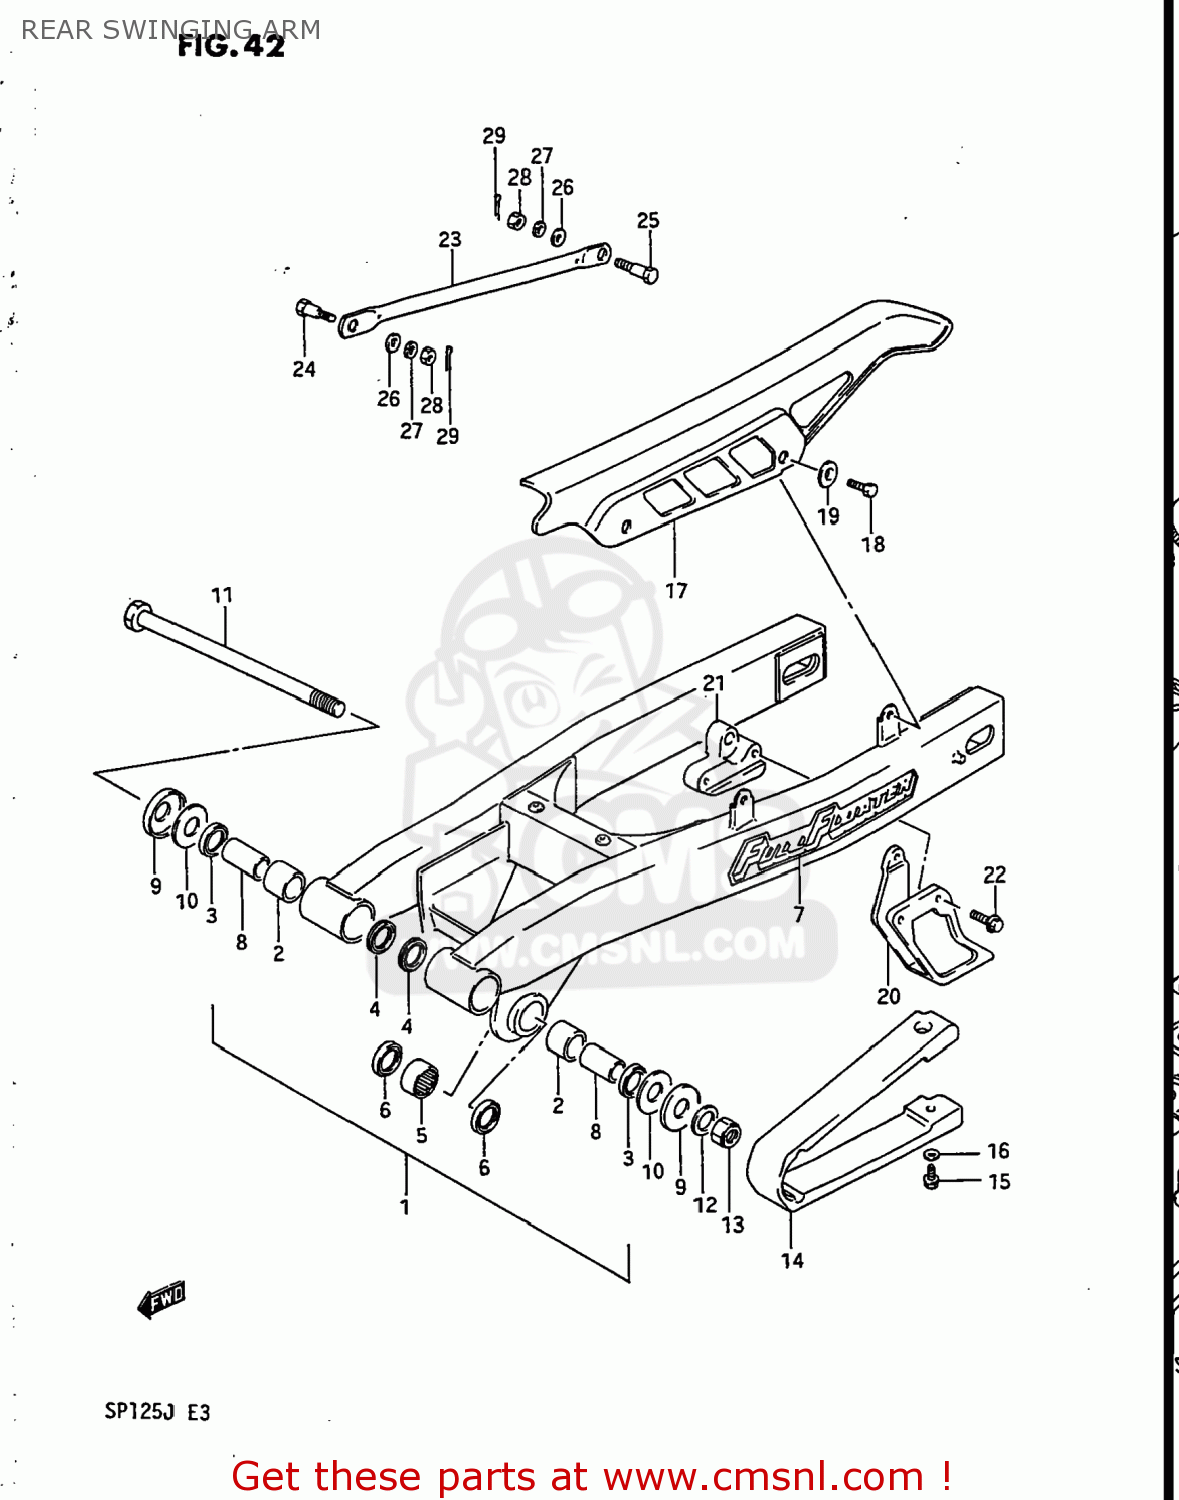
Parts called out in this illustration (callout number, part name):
1	SWING ARM ASSEMBLY,REAR
2	BUSHING,RR SWGARM PIVOT
3	OIL SEAL
4	SEAL,OIL(20X27X5)
5	BEARING
6	SEAL,CUSHION LEVER OUT DUST
7	EMBLEM
8	SPACER,RR SWGARM PVT
9	COVER,RR SWGARM DUST SEAL
10	WASHER
11	SHAFT,REAR SWING ARM
12	WASHER
13	NUT
14	BUFFER,CHAIN TOUCH DEFENSE
15	BOLT
16	WASHER
17	CASE,CHAIN
18	BOLT
19	WASHER
20	GUIDE,CHAIN
21	RUBBER,CHAIN GUIDE
22	BOLT
23	TORQUE LINK,RR
24	BOLT(8X22)
25	BOLT(8X26.5)
26	WASHER
27	LOCK WASHER
28	NUT
29	PIN 20X20
